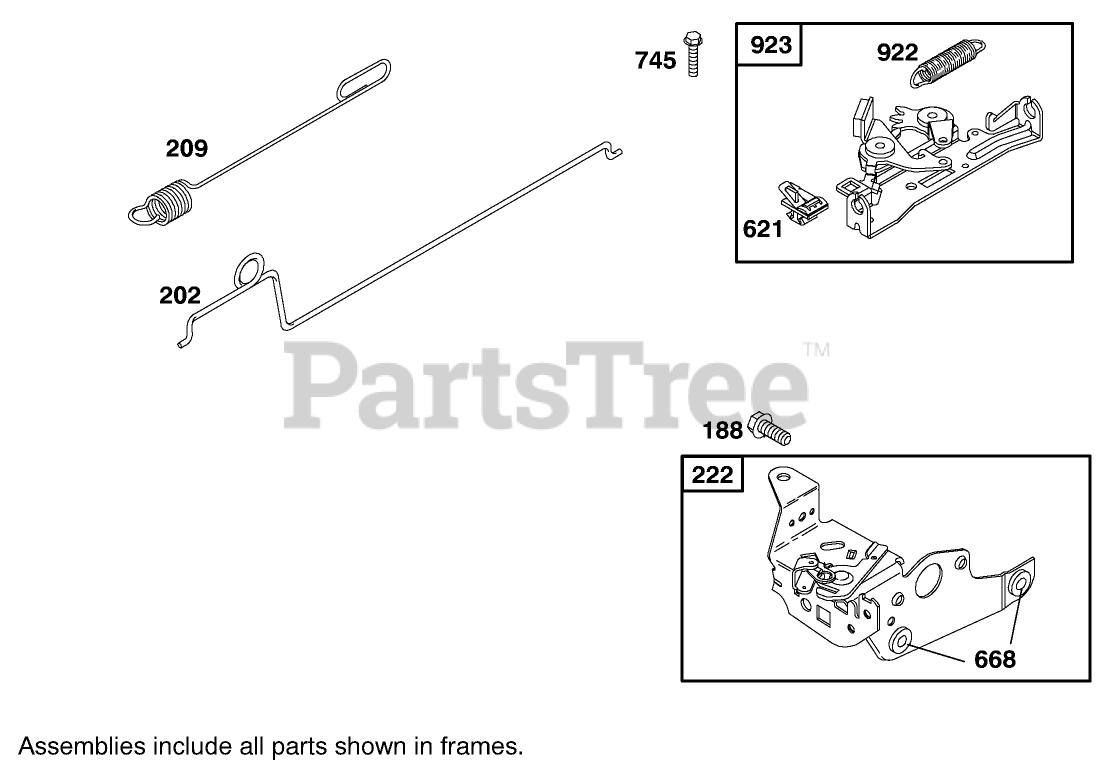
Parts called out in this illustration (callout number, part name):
188	Screw-Hex.
202	Link-Govemor
209	Governor Spring
222	Bracket-Control
621	Switch
668	Spacer
745	Screw-Sem
922	Brake Spring
923	Brake
